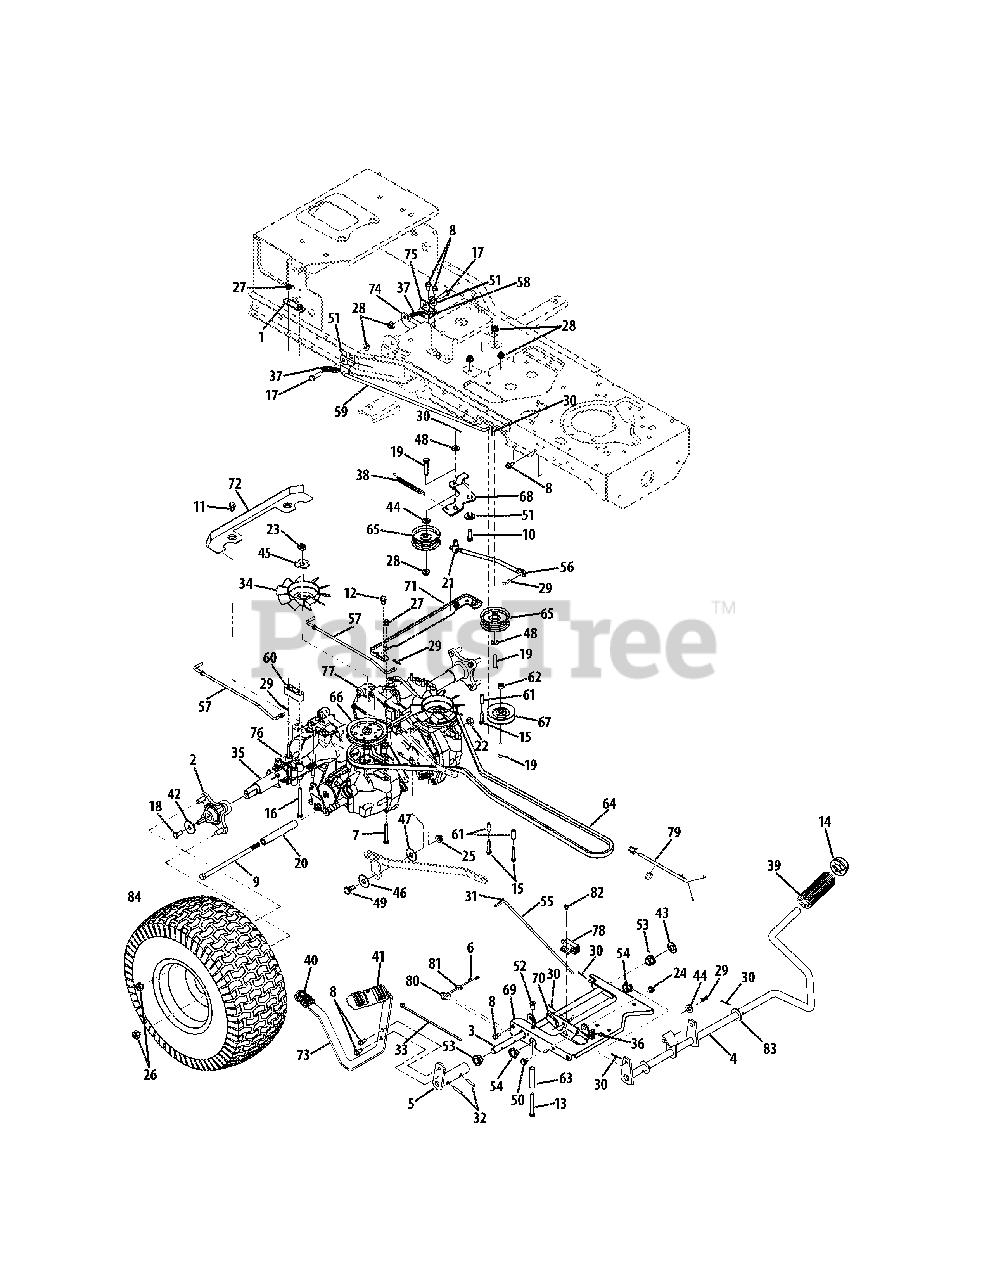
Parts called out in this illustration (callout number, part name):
1	Transmission Mounting Bracket
3	Hydro Control Pedal Shaft Assy.
4	Brake Control Shaft Assembly
6	Hex Washer Screw, #8-18 x .5
7	Hex Screw, 5/16-18 x 2.25
8	Hex Washer Screw, 5/16-12 x .75
9	Hex Screw, 7/16-14 x 8.5
10	Hex Cap Screw, 3/8-16 x 1.0
11	Hex Washer Screw, 1/4-20 x .5
12	Hex Washer Screw, 5/16-18 x .5
13	Hex Screw, 1/4-20 x 2.25
14	Push Cap, 5/8
15	Hex Washer Screw, 1/4-20 x .75
16	Hex Screw, 5/16-18 x 3.5
17	Hex Screw, 3/8-16 x 1.25
18	Hex Lock Screw, 3/8-16 x .75
19	Hex Screw, 3/8-16 x 2.0
20	Spacer, .479 x .75 x 4.97
21	Ferrule, 3/8-24 x .375
22	Hex Lock Nut, 7/16-14
23	Hex Lock Nut, 1/2-20
24	Hex Flange Lock Nut, 5/16-18
25	Hex Lock Nut, 3/8-16
26	Lug Nut, 7/16-14
27	Hex Flange Lock Nut, 5/16-18
28	Hex Flange Lock Nut, 3/8-16
29	Internal Cotter Pin
30	Cotter Pin, 3/32 x 1/0
31	Bow-Tie Cotter Pin
32	Spirol Pin, .25 x 1.25
33	Cable Tie
35	Sleeve, 1.015 x 2.6
36	Compression Spring, .405 x 1.17
37	Extension Spring, .59 x 5.4
38	Extension Spring, .60 x 6.44
39	Foot Pad, 4.0
40	Reverse Pedal Pad
41	Forward Pedal Pad
42	Flat Washer, .39 x 1.5 x .134
43	Flat Washer, .625 x 1.0 x .067
44	Flat Washer, .407 x .812 x .135
45	Hydro Lock Washer
46	Flat Washer, .531 x 1.75 x .09
47	Flat Washer, .406 x 1.5 x .105
48	Flat Washer, .406 x .812 x .051
49	Shoulder Bolt, 3/8-16 x .496 x .336
50	Shoulder Bolt, 5/16-18 x .435 x .160
51	Shoulder Spacer, .625 ID x .169
52	Shoulder Nut, .375 Dia x .5
53	Hex Flange Bearing
54	Hex Flange Bearing, .625 ID Split
55	Park Brake Rod
56	Drive Engage Rod
57	Hydro Bypass Rod
58	LH Brake Rod
59	RH Brake Rod
60	Axle Spacer
61	Spacer, .26 x .372 x 1.42
62	Spacer, .38 x .625 x .265
63	Spacer, .375 x .5 x 2.0
65	Flat Idler Pulley, 2.75
67	Idler Pulley
69	Pedal Support Bracket
70	Park Brake Bracket
71	Support Bracket
72	Belt Keeper Bracket
74	LH Brake Pivot Bracket
75	Brake Pivot Bracket
76	RH Hydro Transmission
77	LH Hydro Transmission
78	Interlock Switch
79	Reverse Jumper Harness
80	Reverse Switch
81	Insulator Nut Plate
82	Shoulder Screw, #10-32 X .5
83	Flat Washer, .64 x 1.24 x .06
